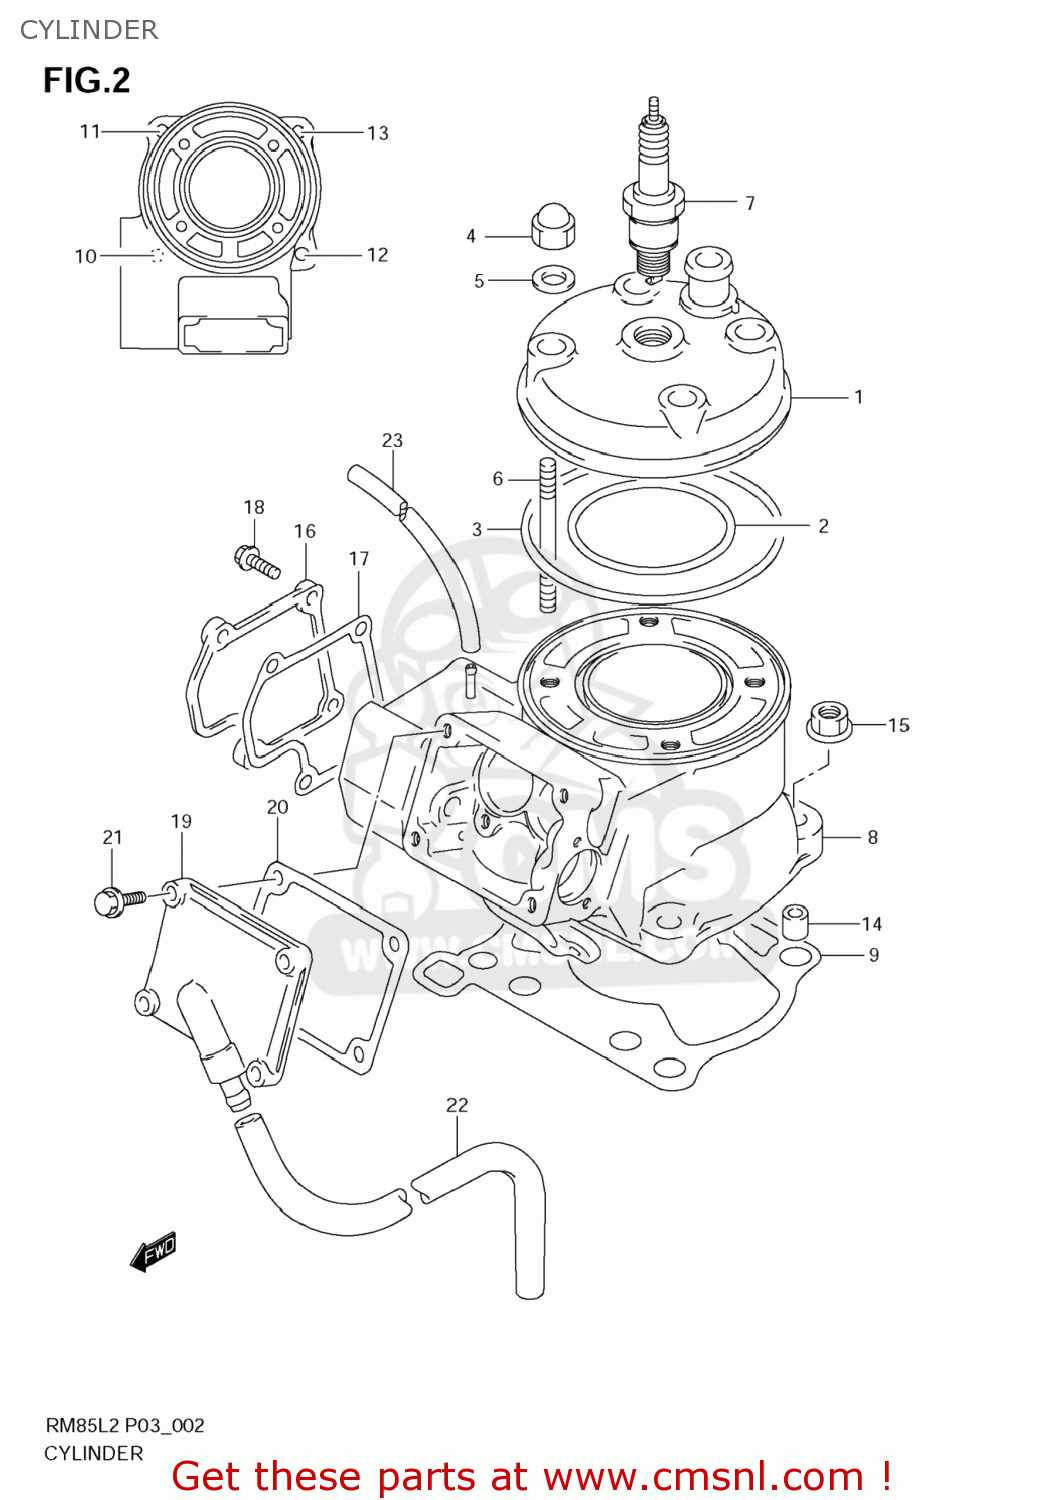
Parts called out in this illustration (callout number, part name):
1	HEAD,CYLINDER
2	O RING,CYLINDER HEAD NO.1
3	O RING,CYLINDER HEAD NO.2
4	NUT
5	GASKET(8.5X17X2.3) (NAS)
6	BOLT,STUD
7	PLUG,SPARK(BR10ES)
8	CYLINDER SET
9	GASKET,CYLINDER (NAS)
10	BOLT,STUD
11	BOLT,STUD
12	BOLT,STUD
13	BOLT,STUD
14	PIN(8.4X11X14)
15	NUT
16	COVER,CYLINDER NO.1
17	GASKET,CYLINDER COVER NO.1 (NAS)
18	BOLT(5X16)
19	COVER,CYLINDER NO.2
20	GASKET,CYL COVER NO.2 (NAS)
21	BOLT(5X16)
22	HOSE(5X8.2X600)
23	HOSE(5X8.2X600)
